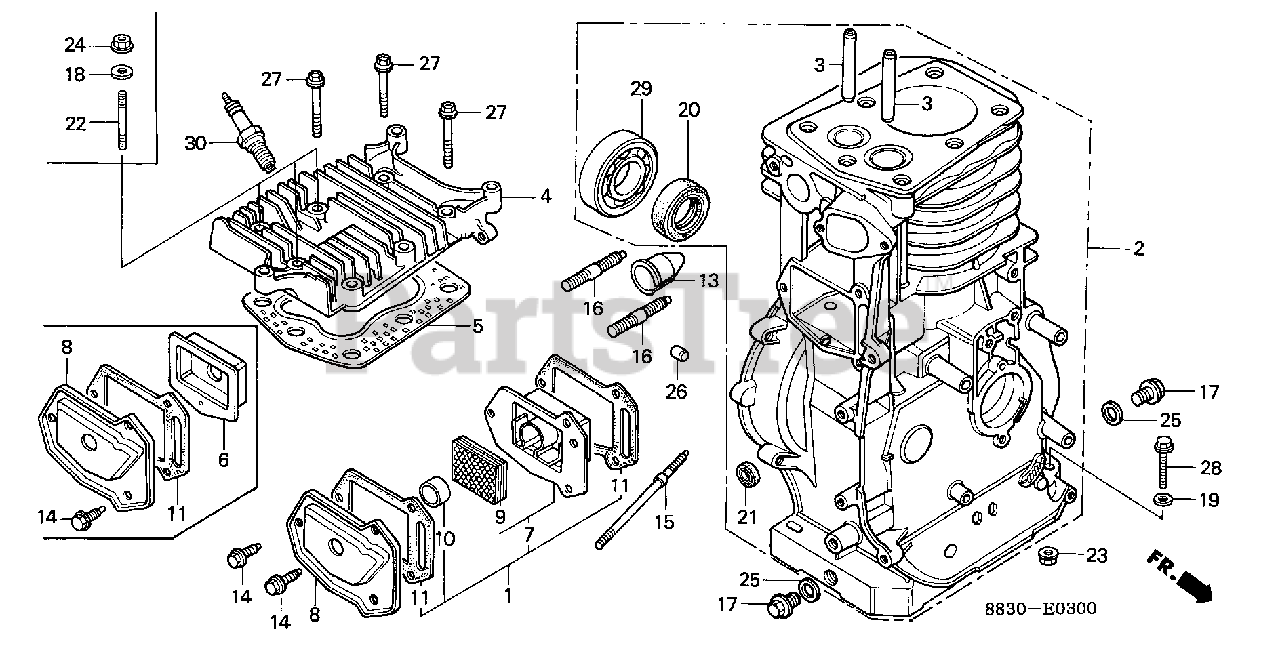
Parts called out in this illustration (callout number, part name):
1	CASE KIT, BREATHER Use up to Engine SN 1556857.
2	CYLINDER ASSY.
3	GUIDE, VALVE (OVER SIZE)
4	CYLINDER HEAD
5	GASKET, CYLINDER HEAD
6	CASE, BREATHER
7	CASE, BREATHER
8	COVER, TAPPET ROOM
9	FILTER, BREATHER
10	SEAL, BREATHER
11	GASKET, TAPPET COVER
14	BOLT, FLANGE (6X12) (CT200)
15	BOLT, STUD (6X95)
15	BOLT, STUD (6X89)
16	BOLT, STUD (8X35)
17	BOLT, DRAIN PLUG (12X15)
20	OIL SEAL (25X41X6)
25	WASHER, DRAIN PLUG (12MM)
26	PIN, DOWEL (8X14)
27	BOLT, FLANGE (8X45)
29	BEARING, RADIAL BALL (6205)
30	SPARK PLUG (B-4H) (NGK)
30	SPARK PLUG (W14F-U) (DENSO)
30	SPARK PLUG (W14FR-U)
30	SPARK PLUG (BP-4HS-10) (NGK)
30	SPARK PLUG (BPR-4HS-10) (NGK)
30	SPARK PLUG (BPR4HS-10)
30	SPARK PLUG (BP4HS-10)
30	SPARK PLUG (W14FP-UL10)
30	SPARK PLUG (W14FPR-UL10)
30	SPARK PLUG (B6HS) (NGK)
30	SPARK PLUG (BR6HS) (NGK)
30	SPARK PLUG (W20FS-U) (DENSO)
30	SPARK PLUG (W20FPR-U10)
